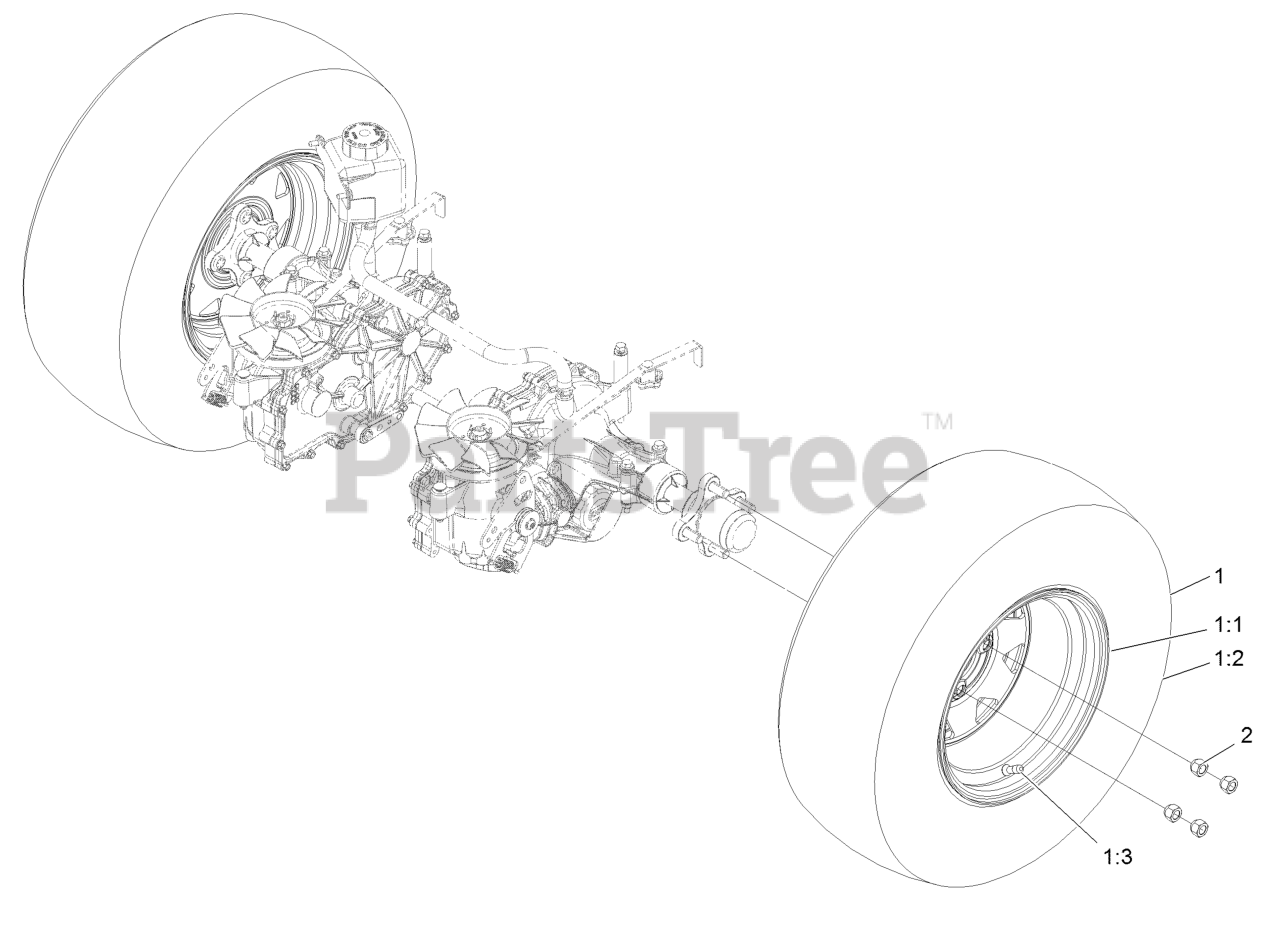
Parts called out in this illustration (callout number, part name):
1	Wheel And Tire ASM
1:2	Tire
1:3	Stem-Valve
2	Nut-Lug 1/2-20
